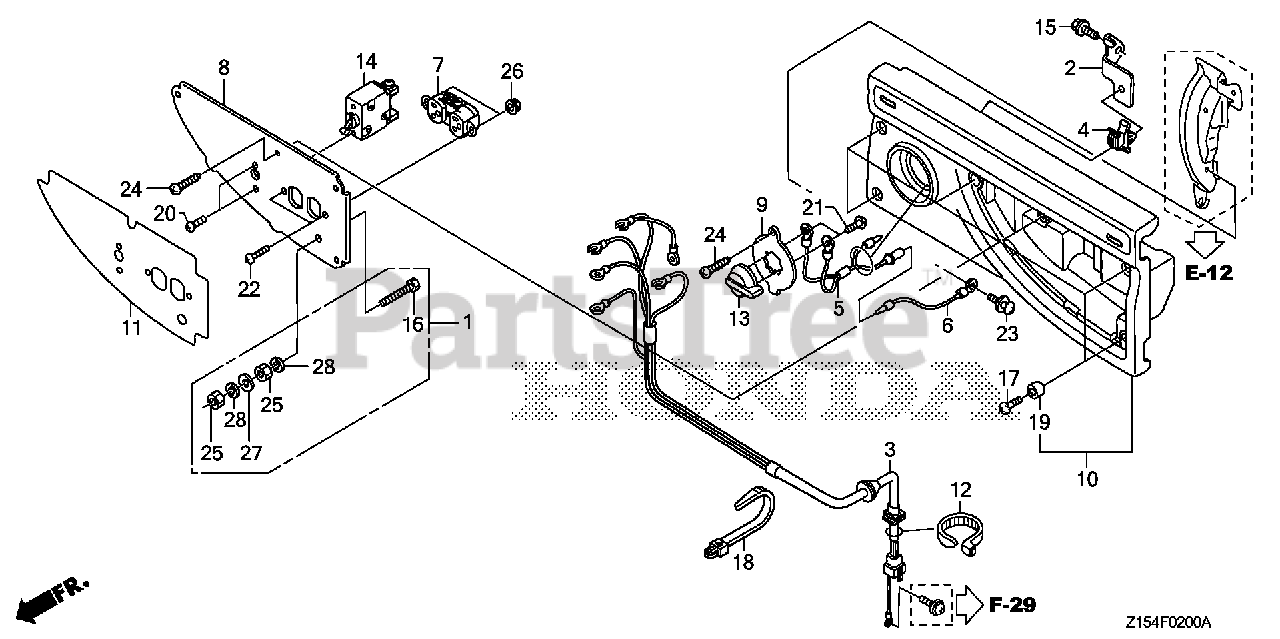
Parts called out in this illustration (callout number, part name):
1	TERMINAL SET, GROUND
2	BRACKET, WIRE HARNESS CLIP
3	WIRE HARNESS ASSY., CONTROL (CX-AH)
4	CLIP B, HARNESS
5	SUB-WIRE ASSY. (A)
6	SUB-WIRE ASSY. (B)
7	RECEPTACLE ASSY. (20A/125V) (MATSUSHITA)
7	RECEPTACLE (20A/125V)
8	PANEL, CONTROL (CX-AH)
9	PANEL, ENGINE SWITCH
10	CASE, CONTROL PANEL *R280R* (POWER RED)
11	MARK, PANEL (CX-A)
12	TIE, CABLE (C)
13	SWITCH ASSY., ENGINE STOP (RED)
14	BREAKER, CIRCUIT (20A)
15	BOLT, FLANGE (6X12) (CT200)
16	BOLT, HEX. (6X20)
17	SCREW, TRUSS (6X18)
18	TIE, CABLE (NATURAL 225X5.0)
19	COLLAR, CONTROL CASE
20	SCREW, PAN (3X5)
21	SCREW, PAN (3X6)
22	SCREW, PAN (4X10)
23	SCREW-WASHER (5X10)
24	SCREW, TAPPING (4X16) (NOT AVAILABLE)
25	NUT, HEX. (6MM)
26	NUT, FLANGE (4MM)
27	WASHER, PLAIN (6MM)
28	WASHER, SPRING (6MM)
